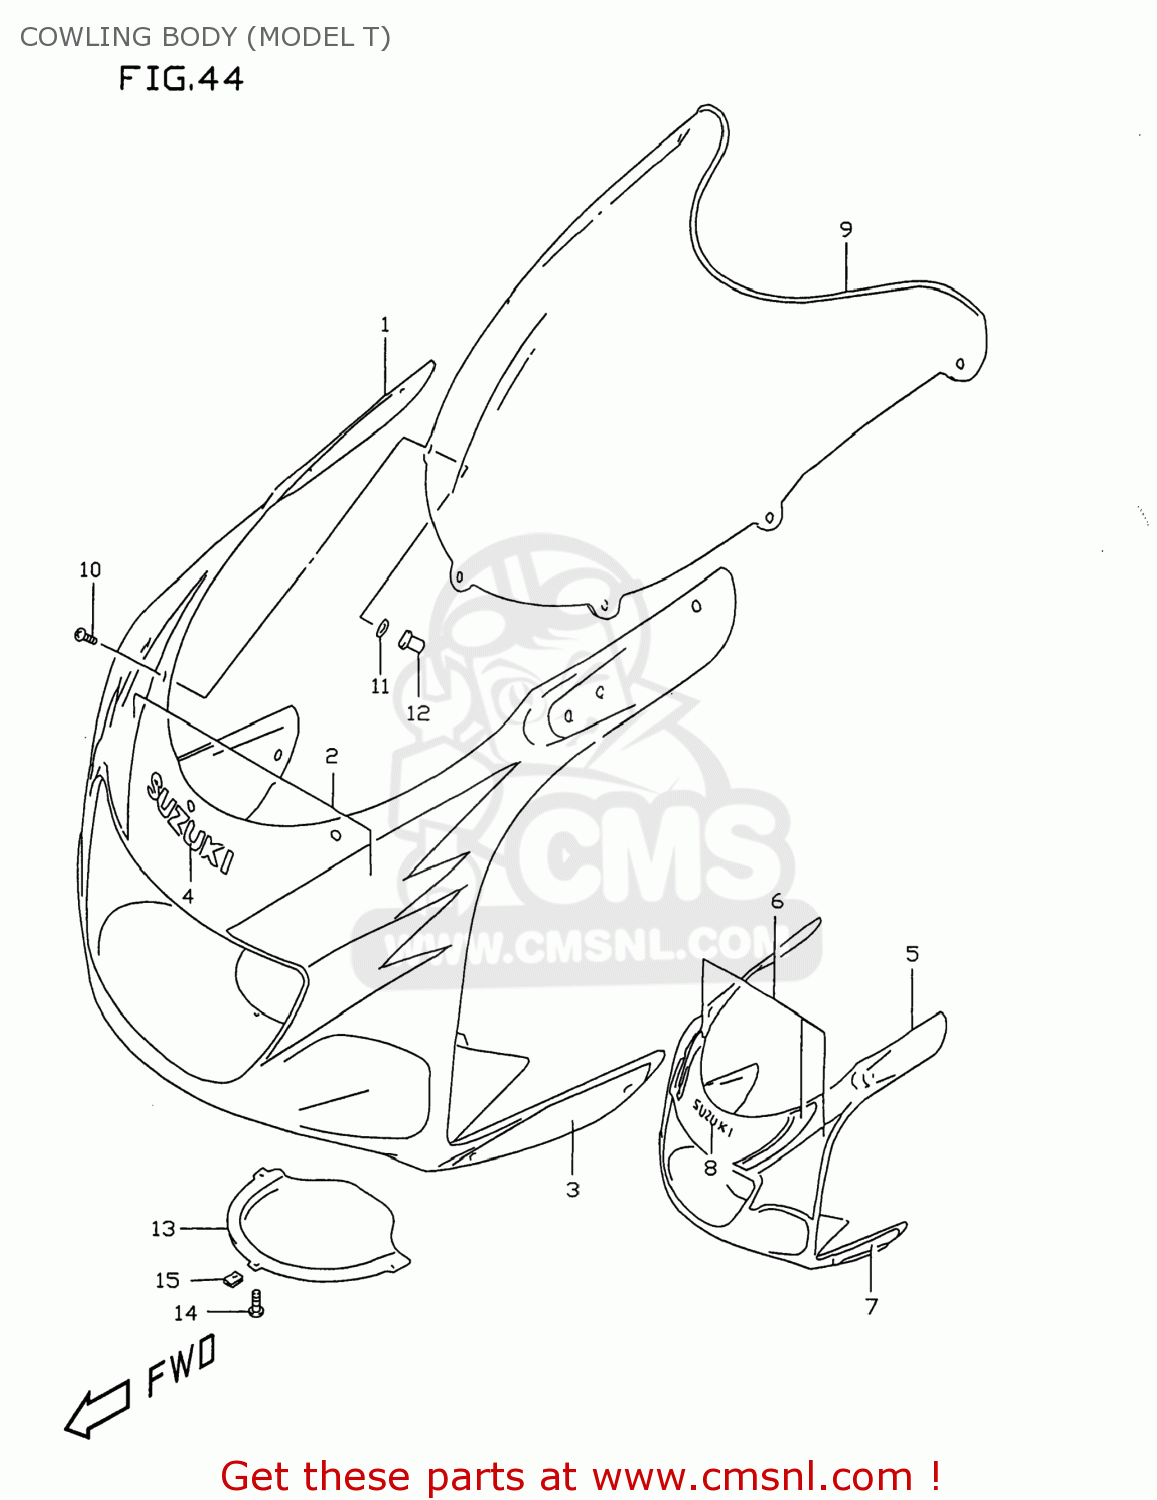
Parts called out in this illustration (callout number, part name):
1	COWLING ASSEMBLY,BODY
2	TAPE SET,COWL BODY FR
3	TAPE,COWL BODY SIDE
4	EMBLEM,COWLING UPR
5	COWLING ASSY,BODY
6	TAPE SET,COWLING BODY
7	TAPE,COWL BODY SIDE
8	EMBLEM,SUZUKI
9	WINDSCREEN
10	SCREW(5X14)
11	WASHER
12	NUT
13	LID,BODY COWLING,LOWER
14	SCREW
15	NUT
